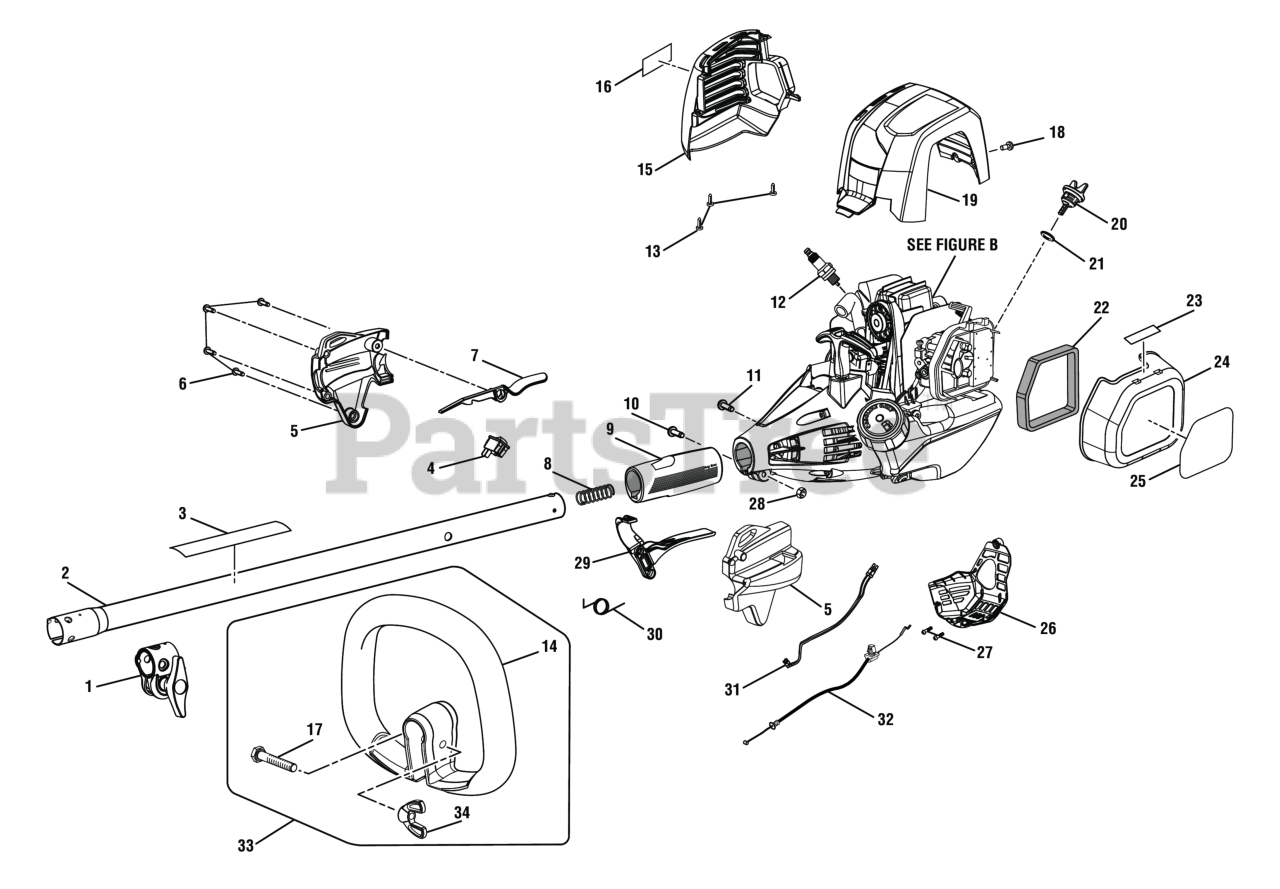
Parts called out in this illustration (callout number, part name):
1	Boom Clamp Assembly
2	Upper Boom Assembly (Inc. Key Nos. 1 and 3
3	Warning Label
4	Stop Switch (Momentary Contact)
5	Control Handle Assembly (Inc. Key No. 6
6	Screw (M4 x 20 mm, T20 Torx Pan Hd. S.T.)
7	TRIGGER LOCKOUT
8	COMPRESSION SPRING
9	Rear Handle Grip
10	Screw (M6 x 20 mm, T27 Torx Button Hd.)
11	Screw (M4 x 8 mm, T25 Torx Pan Hd. T.F.)
12	Spark Plug (Champion RY4C)
13	Screw (M4 x 18 mm, T20 Torx Pan Hd. S.T.)
14	Front Handle
15	Muffler Housing (Inc. Key No. 16)
16	Warning Label (Combustion)
17	Screw (1/4-20 x 40 mm, Cap Hex Hd.)
18	Shoulder Screw (M4 x 11 mm, T25 Torx Pan Hd.)
19	Top Cover
20	Oil Cap/Dipstick (Incl. key no. 12)
22	Air Filter
23	Choke Label
24	Air Filter Cover (Inc. Key No. 23 and 25)
25	Starting Label
26	CE Cover (Bottom Cover)
27	Screw (#6-19 x 1/2 in., Phillips Hd. T.F.)
28	Hex Nut (M6.3 x 1)
29	Throttle Trigger
30	Torsion Spring (Throttle Trigger)
31	Lead Assembly (Inc. Key No. 4)
32	Throttle Cable
33	Auxiliary Handle Assembly
34	Wing Nut (1/4-20, Plastic)
